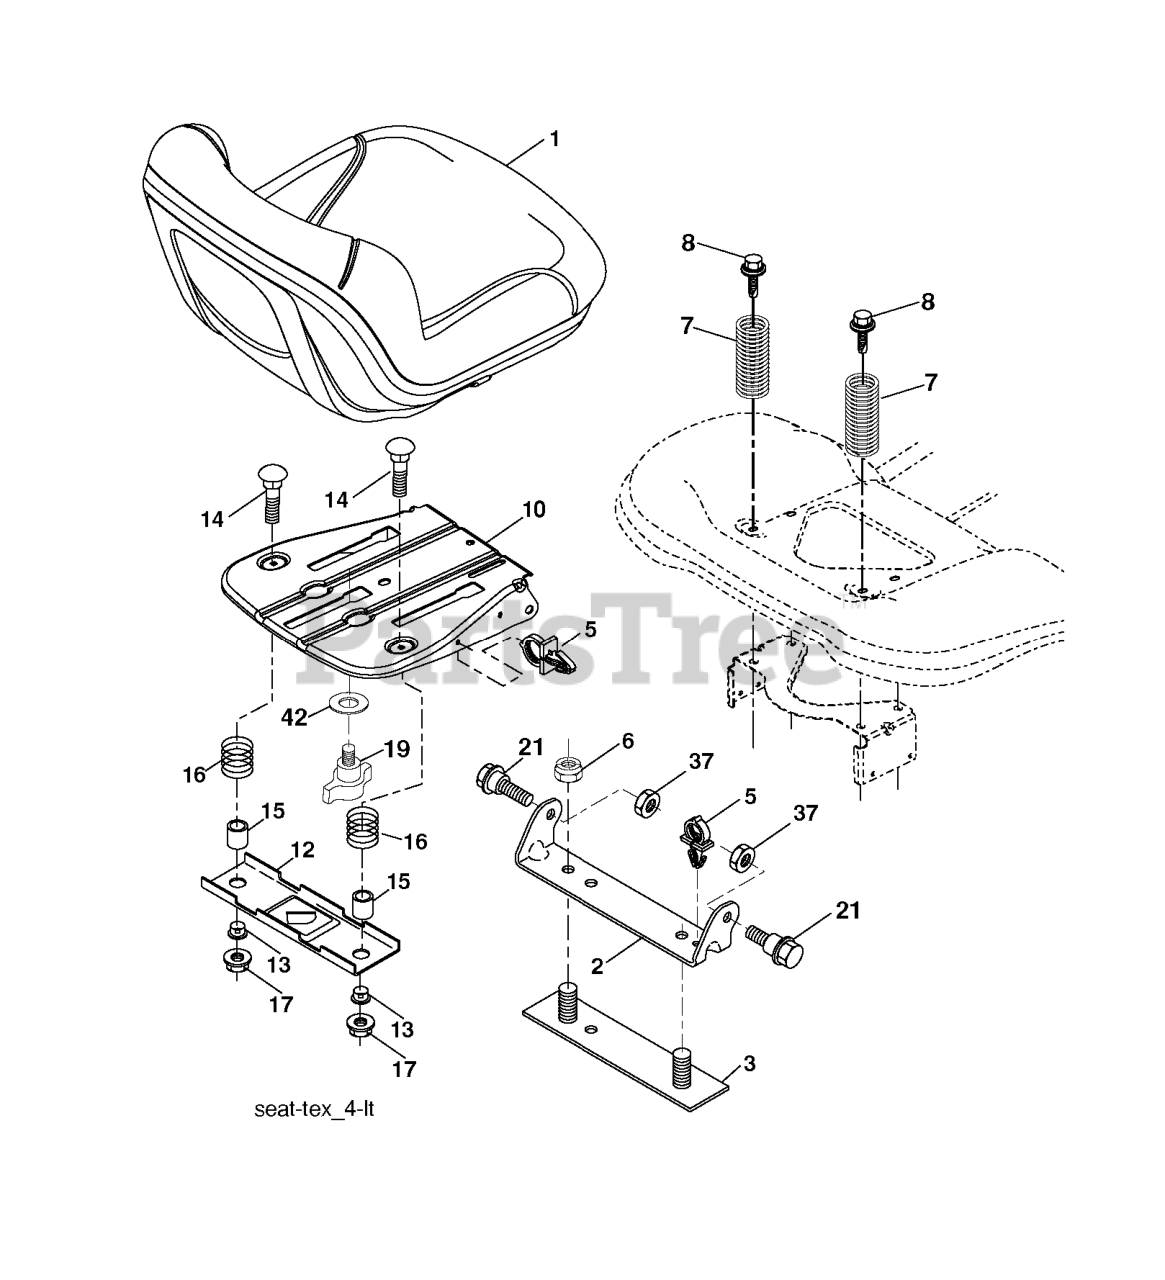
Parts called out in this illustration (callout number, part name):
1	SEAT.TH130.GRY.MILSCO.
2	BRKT.PIVOT.FENDER
3	STRAP
6	NUT
7	SPRING COMPRESSION
8	BOLT.5/16-18UNCX3/4 W/SEMS.BLK
10	PAN.ASM.SEAT.SHORT
12	BRKT.MNT.OPC.SW.SEAT.
14	BOLT.ROUND.HEAD.SQUARE.NECK
15	SPACER SPLIT 28X.96
16	SPRING COMPRESSED
17	NUT T
19	KNOB.SEAT.ADJ.
21	BOLT.SHOULDER.5/16-18
37	NUT.71038.31-18.HEX.NYLOCK
42	WASHER.CUP.SEAT.
